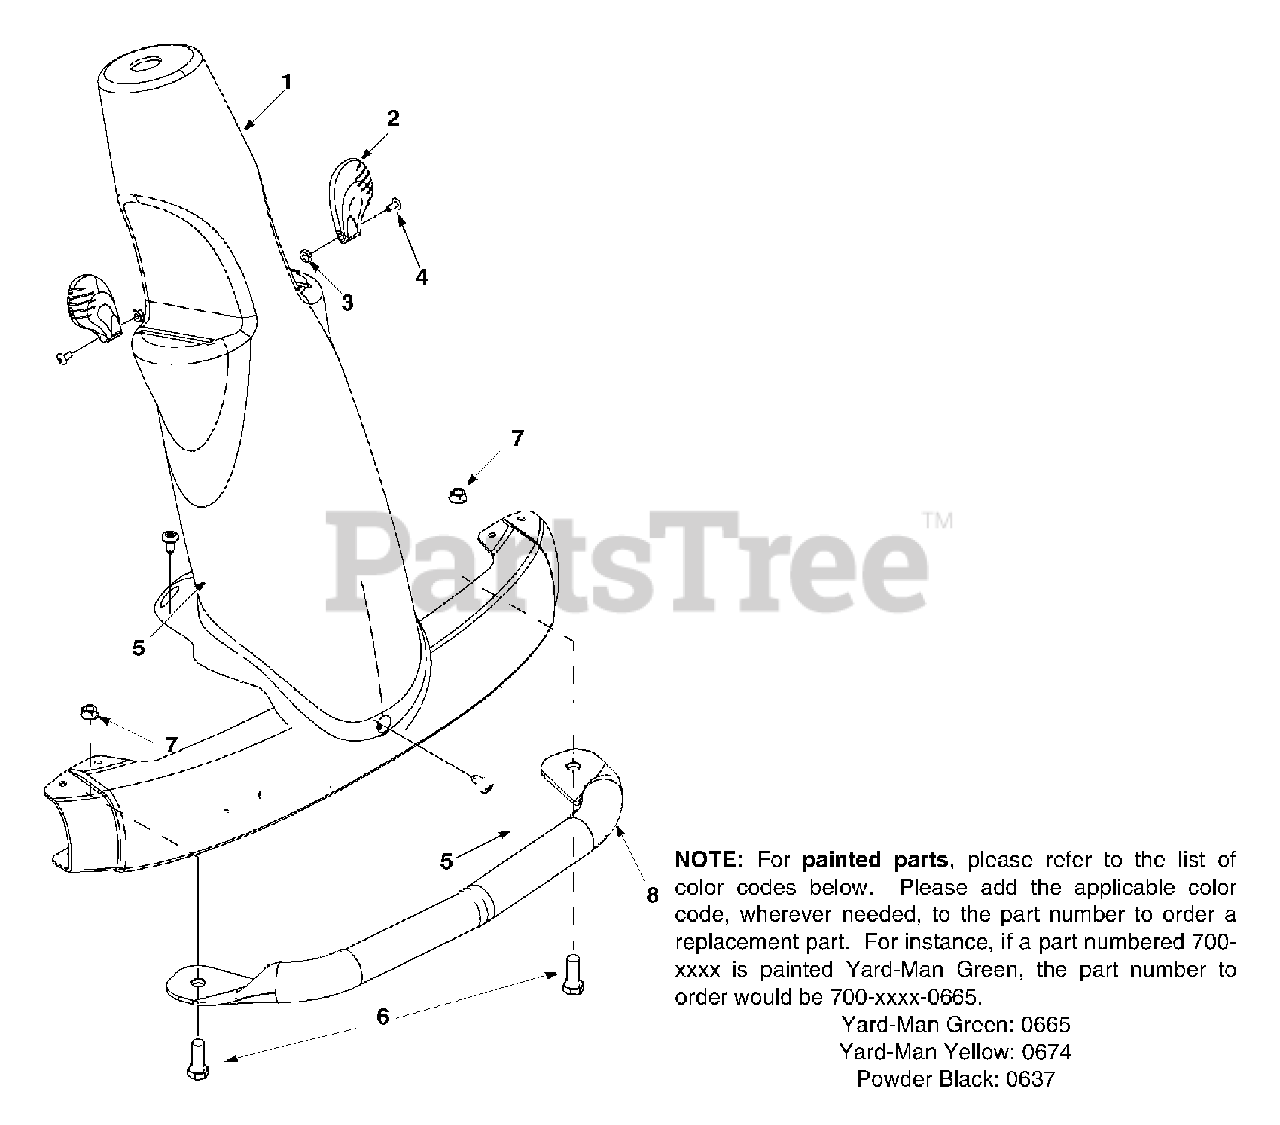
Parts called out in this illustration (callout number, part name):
1	Steering Column: Green
2	Control Knob
3	Hex Nut 8-32
4	Pan Head Machine Screw #8-32
5	Hex Screw TT 1/4-20 x .50"
6	Hex Screw 3/8-16 x 1.0"
7	Lock Nut
